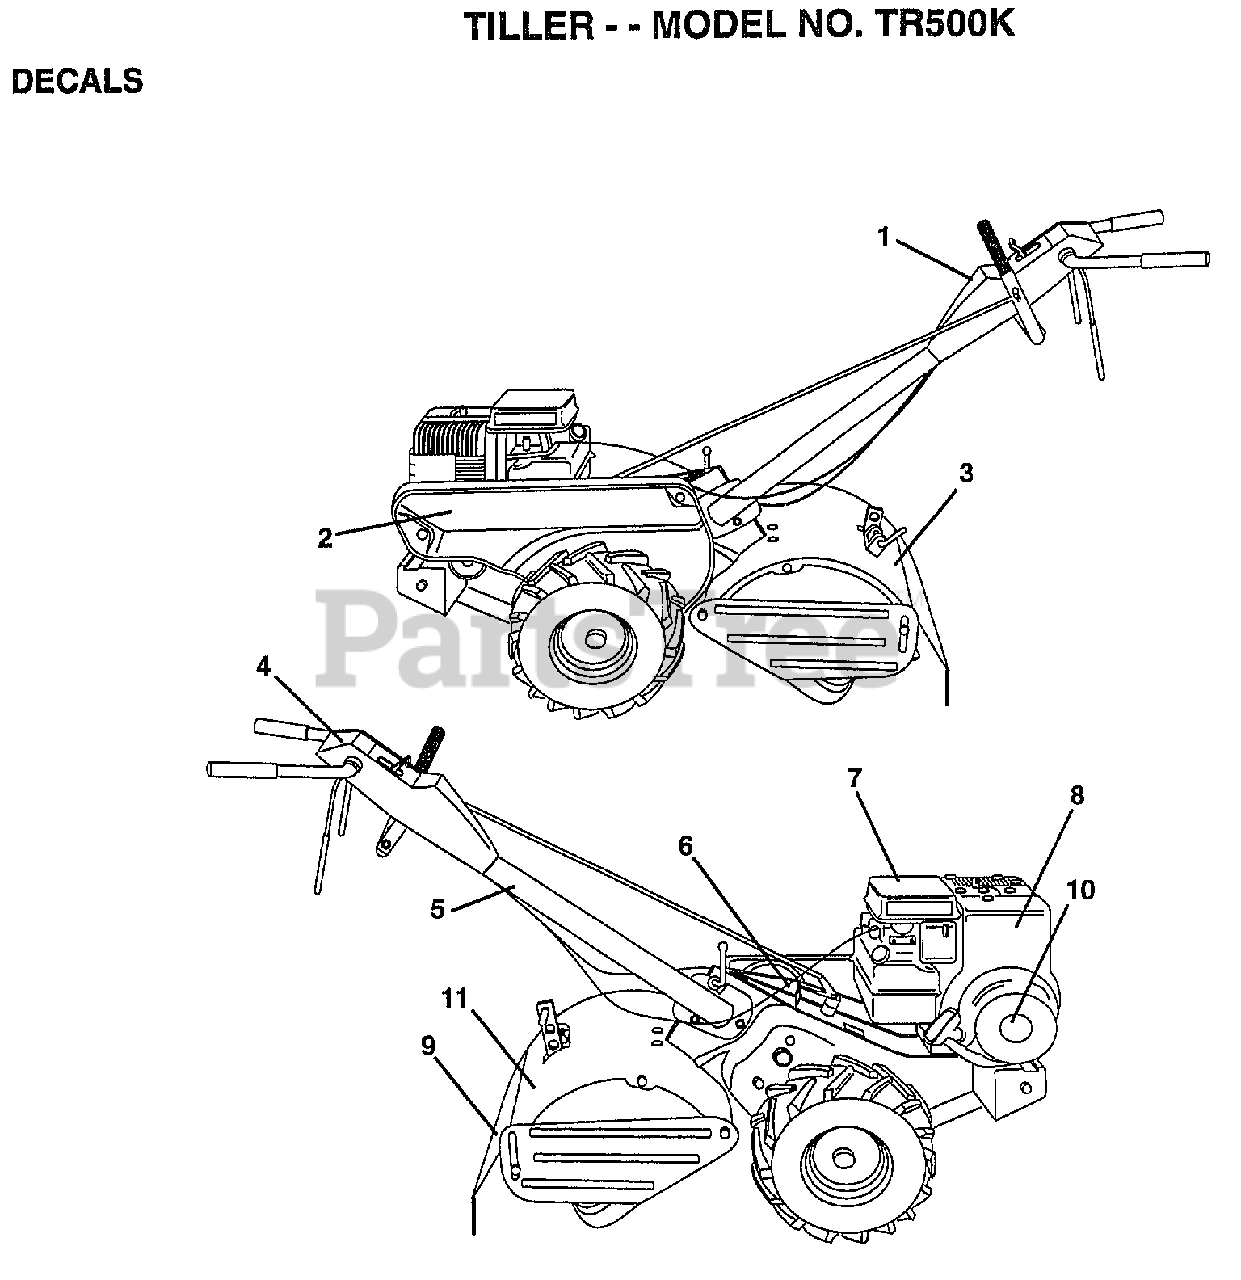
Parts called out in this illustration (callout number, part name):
1	DECAL.PNL.CONTROL
3	DECAL.SHLD.TINE
4	DECAL.INSTRUCTION
5	DECAL TI
6	DECAL CRT
8	DECAL, BRIGGS & STRATTON
9	DECAL TI
11	DECAL.TINE.SHIELD
